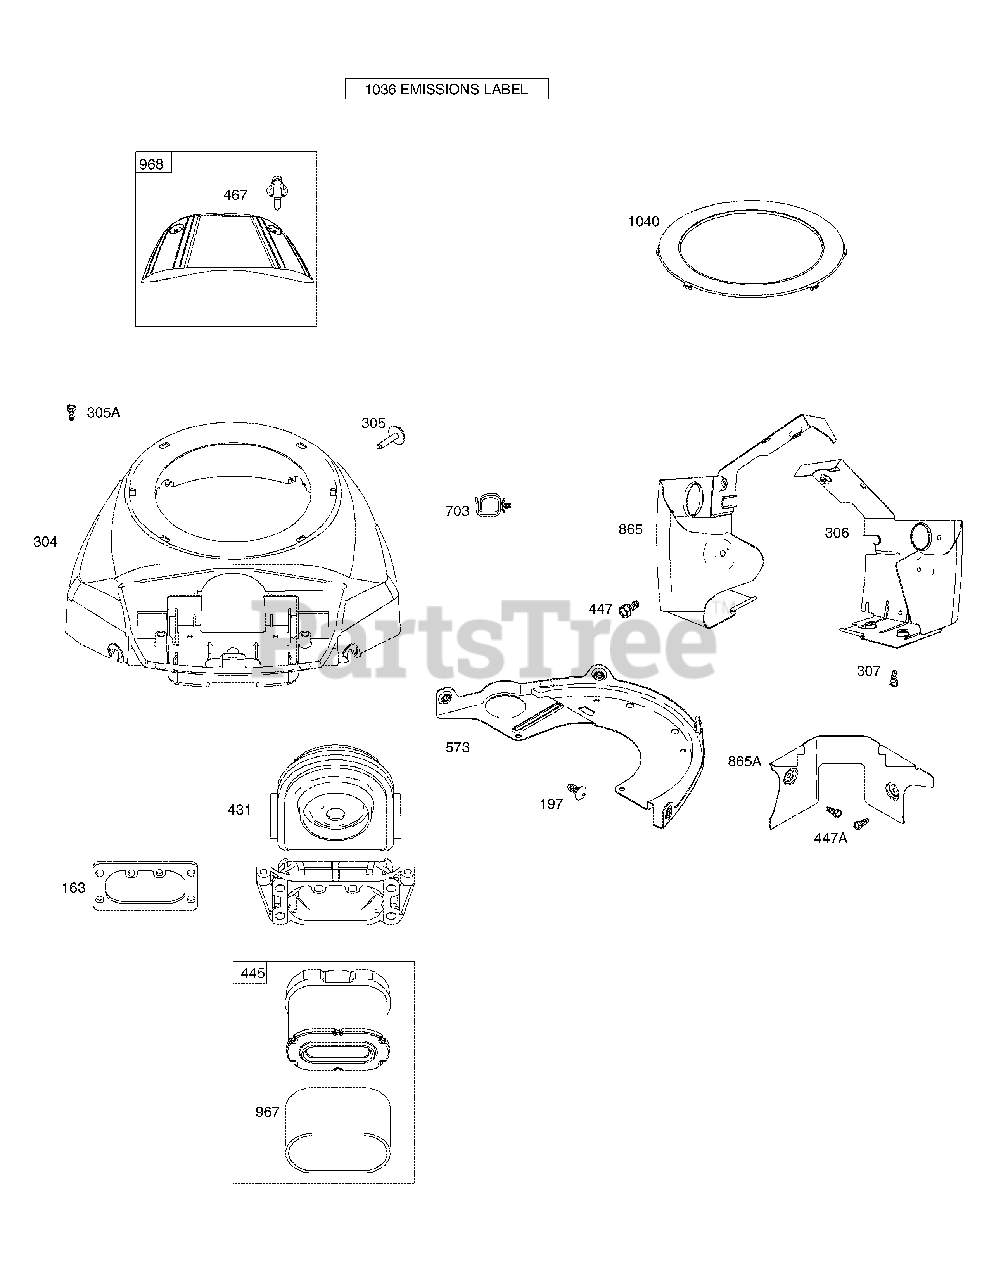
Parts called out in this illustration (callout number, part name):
1	Cylinder Assembly
2	Kit-Bushing/Seal (Magneto Side)
3	Oil Seal (Magneto Side)
4	EngineSump
5	Cylinder Head (Cylinder #1)
5A	Cylinder Head (Cylinder #2)
7	Cylinder Head Gasket
8	Breather Assembly
9	Breather Gasket
10	Screw (Breather Assembly)
11	Breather Tube
12	Crankcase Gasket
13	Screw (Cylinder Head)
15	Oil Drain Plug
16	Crankshaft
20	Oil Seal (PTO Side)
22	Screw (Crankcase Cover/Sump)
23	Flywheel
24	Flywheel Key
25	Piston Assembly (Standard)
25	Piston Assembly (.020" Oversize)
26	Ring Set (Standard)
26	Ring Set (.020" Oversize)
27	Piston Pin Lock
28	Piston Pin
29	Connecting Rod
32	Screw (Connecting Rod)
33	Exhaust Valve
34	Intake Valve
35	Valve Spring (Intake)
36	Valve Spring (Exhaust)
40	Valve Retainer
42	Valve Keeper
45	Valve Tappet
48	Short Block
50	Intake Manifold
51	Intake Gasket
51A	Intake Gasket
53	Stud (Carburetor)
54	Screw (Intake Manifold)
73	Rotating Screen
74	Screw (Rotating Screen)
75	Washer (Flywheel)
95	Screw (Throttle Valve)
98	Idle Speed Kit
104	Float Hinge Pin
105	Float Needle Valve
108	Choke Valve
117	Main Jet (Standard) (Left Jet)
117A	Main Jet (Standard) (Right Jet)
118	Main Jet (High Altitude) (Left Jet)
118A	Main Jet (High Altitude) (Right Jet)
121	Carburetor Overhaul Kit
125	Carburetor
130	Throttle Valve
131	Throttle Shaft Kit
133	Carburetor Float
135	Fuel Transfer Tube
137	Float Bowl Gasket
141	Choke Shaft Kit
142	Carburetor Nozzle
146	Timing Key
150	Nozzle Gasket
163	Air Cleaner Gasket
165	Nut (Ring Gear)
177	O-Ring Seal (Dipstick)
187	Fuel Line (Cut to Required Length)
188	Screw (Control Bracket)
192	Rocker Arm Adjuster
197	Screw (Back Plate)
209	Governor Spring (Yellow/Black)
211	Governed Idle Spring (Orange)
212	Throttle Link
216	Choke Link
217	Choke Return Spring
219	Governor Gear
220	Washer (Governor Gear)
221	Governor Cup
222	Control Bracket
227	Governor Control Lever
231	Screw (Choke Valve)
239	Oil Pressure Switch
240	Fuel Filter
250	Breather Retainer
252	Oil Collector
265	Casing Clamp
267	Screw (Casing Clamp)
276	Sealing Washer (Fuel Solenoid)
278	Washer (Governor Control Lever)
287	Screw (Dipstick Tube)
304	Blower Housing
305	Screw (Blower Housing)
305A	Screw (Blower Housing to Intake Elbow)
306	Cylinder Shield (Cylinder #2)
307	Screw (Cylinder Shield) (1.4-20 x 2.3)
309	Starter Motor
310	Screw (Starter Motor)
332	Nut (Flywheel)
333	Magneto Armature
334	Screw (Magneto Armature)
337	Spark Plug
358	Engine Gasket Set
385	Screw (Fuel Pump)
387	Fuel Pump
404	Washer (Governor Crank)
415	Plug (Oil Pressure Switch)
418	Carburetor Plate
431	Intake Elbow
445	Air Cleaner Cartridge Filter
447	Screw (Air Guide Cover) 10-24 x 7.16)
447A	Screw (Air Guide Cover)
467	Air Cleaner Knob
474	Alternator
501	Regulator
503	Starter Strap
505	Nut (Governor Control Lever)
510	Starter Drive
513	Drive Clutch
523	Dipstick
524	Dipstick Tube Seal
525	Dipstick Tube
526	Screw (Regulator)
544	Starter Armature
552	Governor Crank Bushing
552A	Governor Crank Bushing
562	Screw (Governor Control Lever)
573	Back Plate
579	Nut (Starter Cable)
601	Hose Clamp (Black)
601A	Hose Clamp (Green)
615	Governor Shaft Retainer
616	Governor Crank
617	O-Ring Seal (Intake Manifold) (Red)
628	Screw (Fuel Pump Bracket)
633	Choke Seal/Throttle Shaft
635	Spark Plug Boot
654	Nut (Carburetor)
668	Spacer (Rotating Screen)
668A	Spacer (Rotating Screen)
672	Carburetor Plate Gasket
691	Governor Shaft Seal
695	Screw (Ring Gear)
697	Screw (Drive Cap)
718	Locating Pin
741	Timing Gear
742	E-Ring Retainer (Governor Crank)
750	Screw (Oil Pump Cover)
783	Pinion Gear
788	Fuel Pump Bracket
789	Wiring Harness
798	Screw (Rocker Arm)
803	Starter Housing
847	Dipstick/Tube Assembly
851	Spark Plug Terminal
865	Air Guide Cover (Cylinder #1)
865A	Air Guide Cover (Valley)
868	Valve Seat
877	Alternator Wire/Connector
877A	Alternator Wire/Connector
883	Exhaust Gasket
914	Screw (Rocker Cover)
918	Vacuum Hose
943	O-Ring Seal (Oil Pump Cover)
947	Fuel Solenoid
965	Oil Pump Cover
967	Pre-Cleaner Filter
968	Air Cleaner Cover
975	Float Bowl
987	Throttle Shaft Seal
1005	Flywheel Fan
1013	Oil Filter Nipple
1017	Oil Pump Screen
1022	Rocker Cover Gasket
1023	Rocker Cover (Cylinder #1)
1023A	Rocker Cover (Cylinder #2)
1026	Push Rod (Exhaust)
1026A	Push Rod (Intake)
1027	Oil Filter
1029	Rocker Arm
1036	Emissions Label
1040	Trim Plate
1051	Retaining Ring (Starter Drive)
1058	Operator's Manual
1059	Screw/Washer Kit (Alternator)
1070	Screw (Flywheel Fan)
1090	Brush Retainer
1095	Valve Gasket Set
1100	Rocker Arm Pivot
1119	Screw (Alternator)
1124	O-Ring Seal (Fuel Transfer Tube)
1124A	O-Ring Seal (Fuel Transfer Tube)
1126	Screw (Fuel Transfer Tube)
1127	Screw (Fuel Bowl)
1128	Screw (Carburetor Nozzle)
1169	Screw (Carburetor Plate)
1329	Replacement Engine
